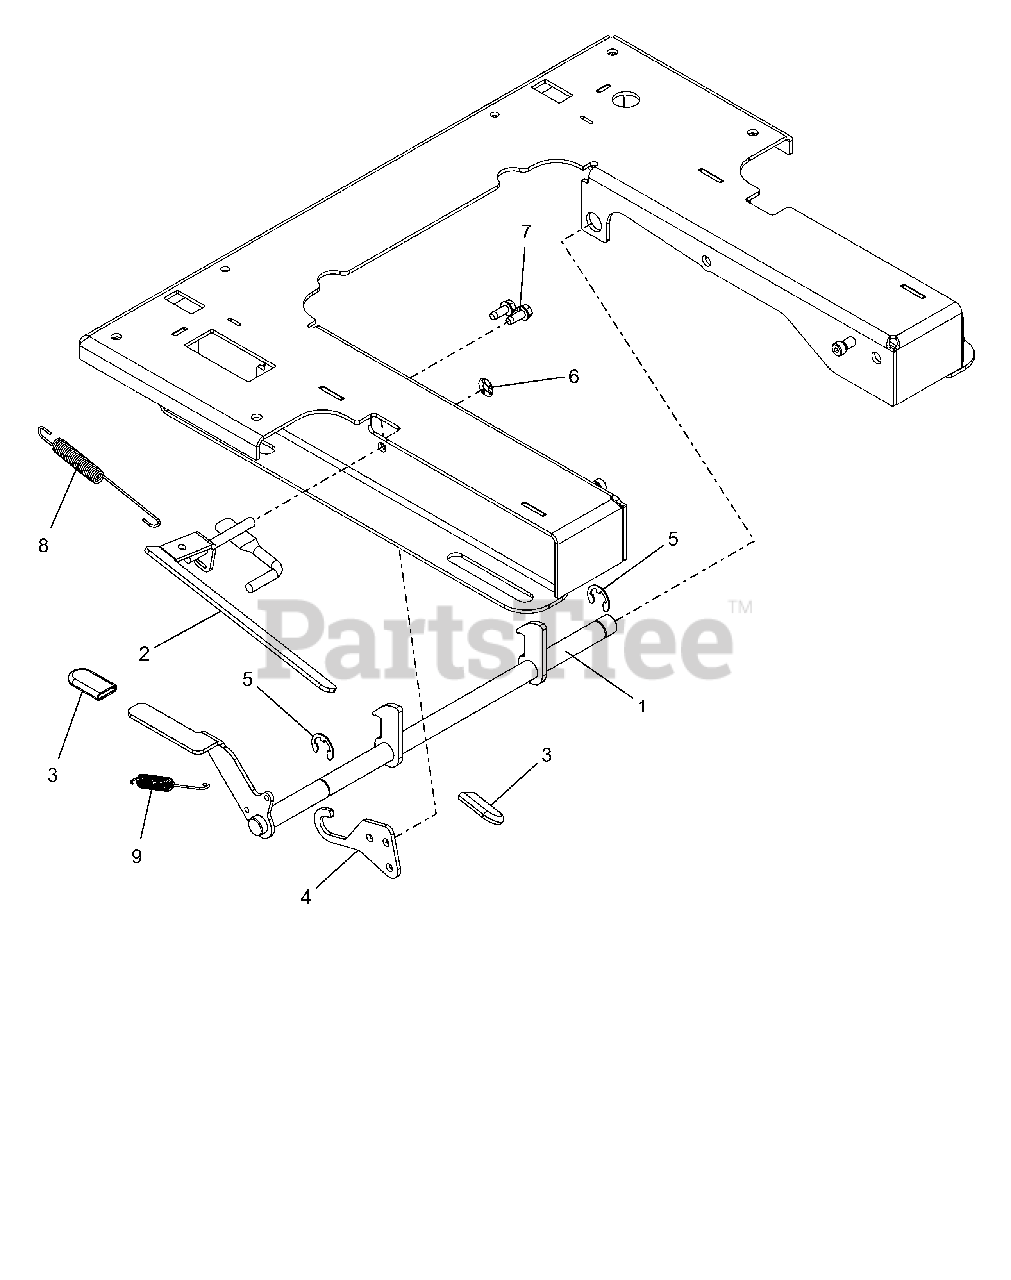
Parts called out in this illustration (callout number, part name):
1	WLDMT, COMPACT PRO SEAT LATCH
2	WLDMT, COMPACT PRO SEAT LATCH
3	GRIP, SEAT LEVER, GREY
4	BRKT, SEAT LATCH MOUNTING
5	RG-RTNG-EXT .625X.042
6	NUT-PUSH .312
7	SCR,TAP .25-20X.625 HWH ZCC
8	SG-TENS .06X.482X5.35
9	SG-TENS .043X.44X3.31 WLD 5.8
